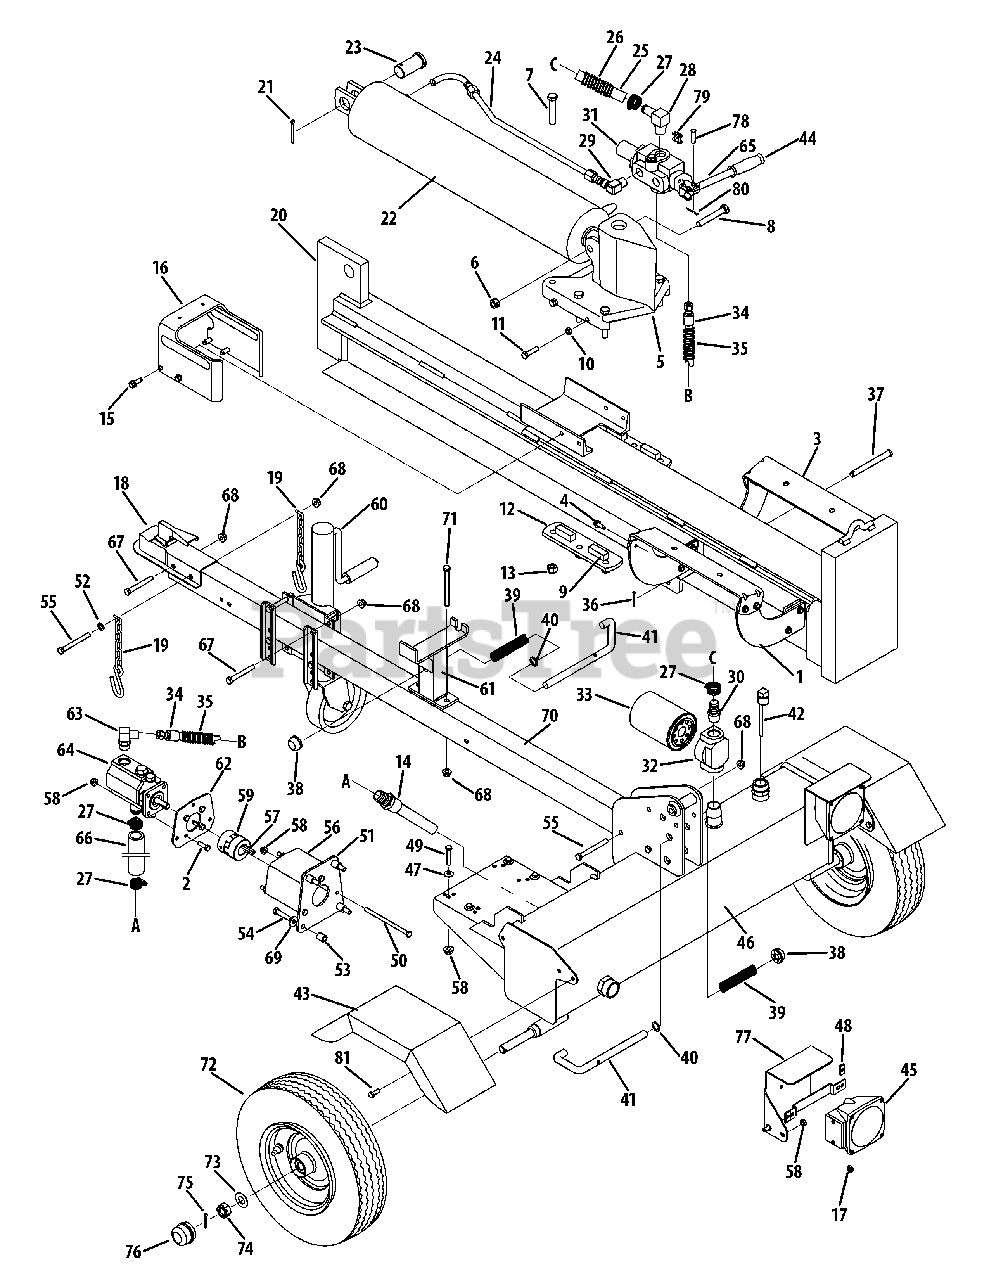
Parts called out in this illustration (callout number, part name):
1	Log Tray Bracket
2	Hex Screw, 5.16-18 x 1.00
3	Log Tray Bracket
4	TT Screw, 5.16-18 x .750
5	Wedge Assembly
6	Lock Nut, 1.2-13
7	Hex Cap Screw, 1.2-20 x 2.75
8	Hex Cap Screw, 1.2-13 x 3.25
9	Adjustable Gib
10	Hex Jam Nut, 3.8-24
11	Hex Cap Screw, 3.8-24 x 1.5
12	Back Plate
13	Hex Lock Nut, 1.2-20
14	Inlet Filter
15	Hex Washer Screw, 3.8-16 x 1.0
17	Jam Nut, 3.8-16
18	2-inch Hitch Coupler
20	Beam Assembly
21	Cotter Pin
22	Hydraulic Cylinder 31/33 Ton
23	Clevis Pin
24	Hydraulic Tube
25	Return Hose, 3.4"ID x 44"
26	Hose Guard
27	Hose Clamp, 5.8"
28	Return Elbow
29	90 Degree Solid Male Adapter
30	3.4"Hose Adapter
31	Control Valve
32	Filter Housing
33	Oil Filter
34	High Pressure Hydraulic Hose
35	Hose Guard
36	Cotter Pin, 18"
37	Hinge Pin, 1.2 x 4.8"Lg.
39	Compression Spring 4"
40	Flat Washer, .635 ID x .93 OD
41	Locking Rod
42	Vented Dipstick
45	Tail Light Assembly
45	Tail Light - RH
45	Tail Light - LH
45	Harness - Wire
46	Frame Assembly, 7.0 Gal
47	Bell Washer, 340 x .872 x .060
48	Tin Nut Clip, 1.4-20
49	Hex Cap Screw, 5.16-18 x 1.75
50	Hex Cap Screw, 5.16-18 x 5.50
51	Front Support Bracket Coupling
52	Flat Washer, .375 x .738 x .063
53	Spacer, .385 x .623 x .750
54	Hex Cap Screw, 3.8-16 x 1.75
55	Hex Cap Screw, 3.8-16 x 3.50
56	Coupling Shield
58	Hex Flange Lock Nut, 5.16-18
59	Flex Coupling
59	Set Screw, 1.4-20 x .38
59	Coupling, .500
59	Coupling, 1.00
59	Spider Coupling
60	Adjustable Jack Stand
61	Support Beam Assembly
62	Rear Coupling Support Bracket
63	Adapter, 7.8-14
65	Hydraulic Valve Control
66	Suction Hose
67	Hex Cap Screw, 3.8-16 x 3.0
68	Flange Lock Nut, 3.8-16
69	Lock Washer, 3.8
70	Tube
71	Hex Cap Screw, 3.8-16 x 4.0
72	Wheel Assembly
72	Tire 4.80 X 8
72	Valve
72	Rim Assembly
72	Dust Seal
72	Roller Bearing
73	Flat Washer, .76"ID x 1.5"OD
74	Slotted Nut, 3.4-16
75	Cotter Pin, 5.32"x 1-1.4"
77	Light Bracket Assembly LH
77	Light Bracket Assembly RH
78	Clevis Pin
79	Valve Handle Link
80	Cotter Pin
81	TT Screw, 5.16-18 x .875
